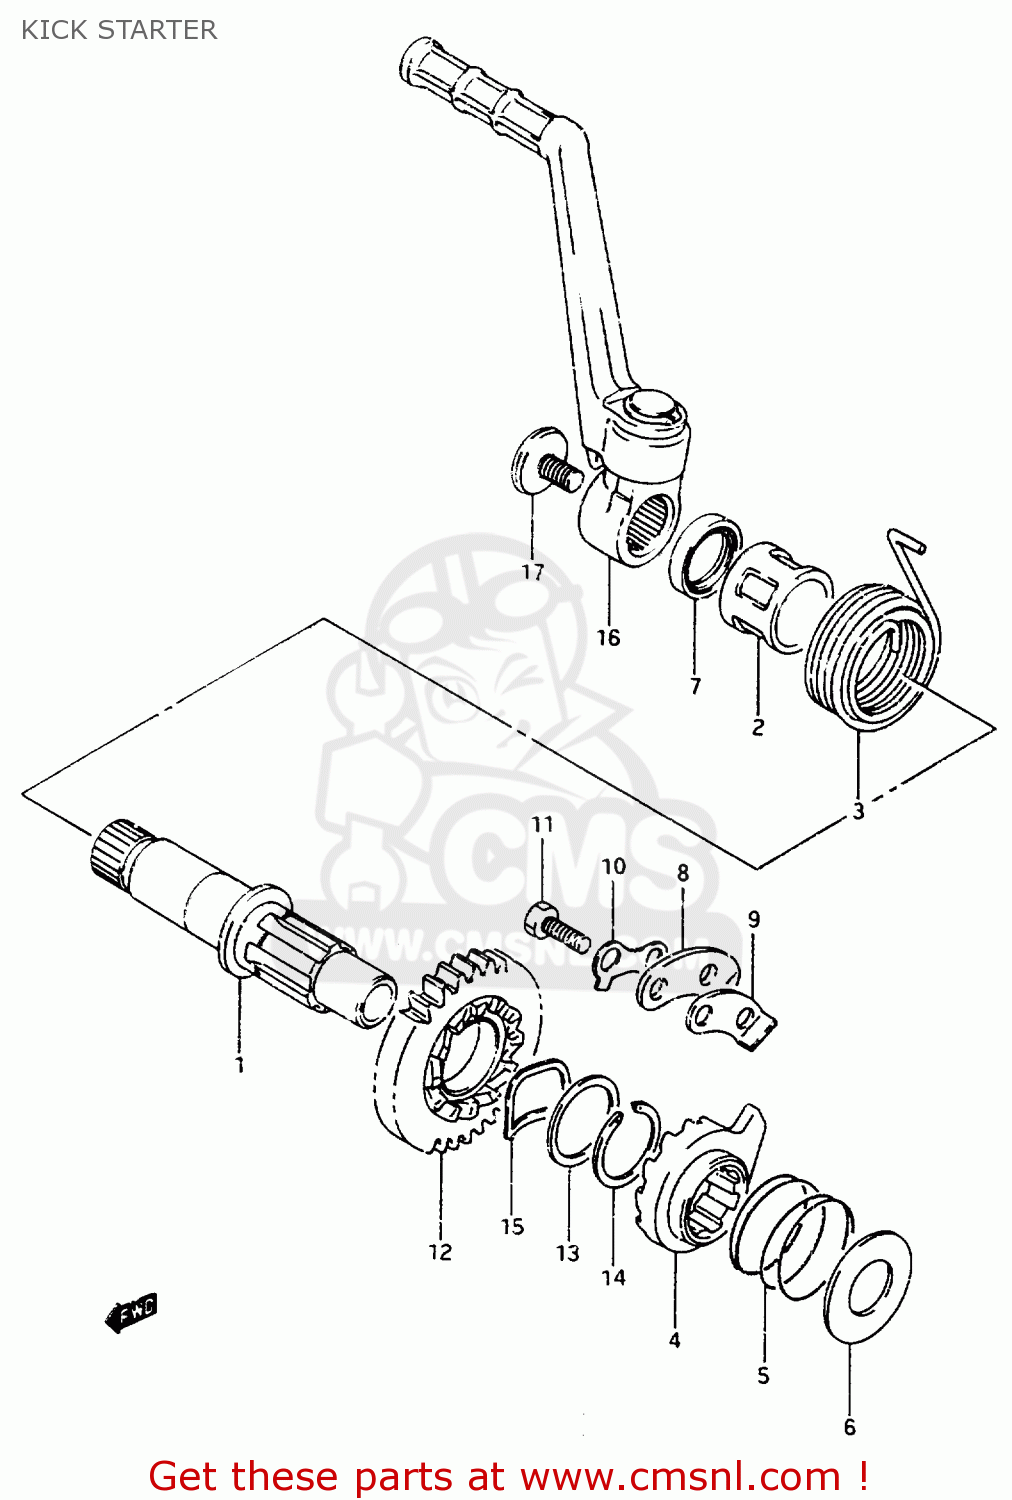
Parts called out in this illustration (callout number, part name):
1	SHAFT,KICK STARTER
2	GUIDE,KICK STARTER SFT SPRING
3	SPRING
4	STARTER, KICK
5	SPRING
6	WASHER
7	SEAL,OIL(20X27X6)
8	GUIDE,KICK STARTER
9	STOPPER,KICK STARTER
10	WASHER
11	BOLT
12	GEAR, KICK STARTER DRIVE (NT:29)
13	SHIM
14	CIRCLIP
15	WASHER
16	LEVER ASSY, KICK STARTER
17	BOLT
